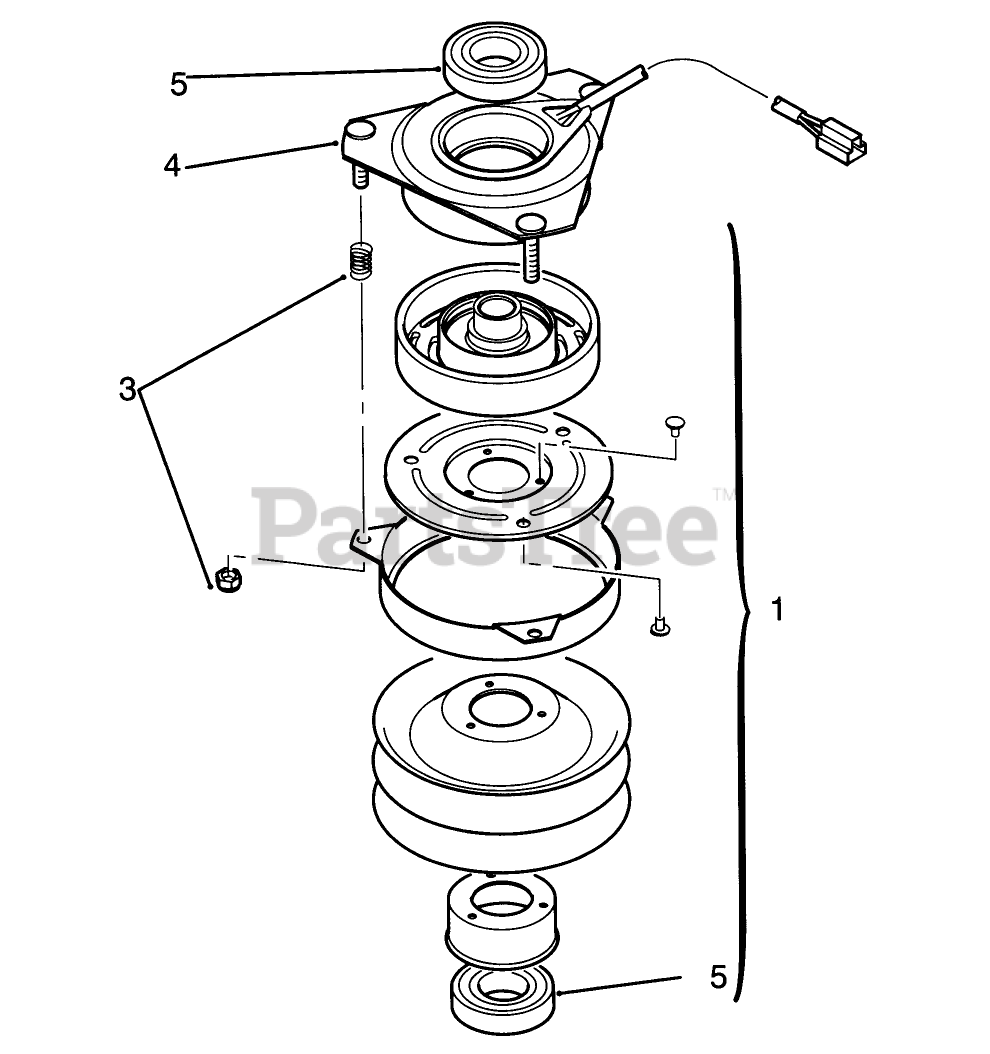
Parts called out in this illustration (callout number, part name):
1	ROTOR & ARMATURE ASSY
3	ACCESSORY PKG SRVC PART
4	FIELD ASSY (SRVC PART)
5	BEARING-ELEC CLUTCH
